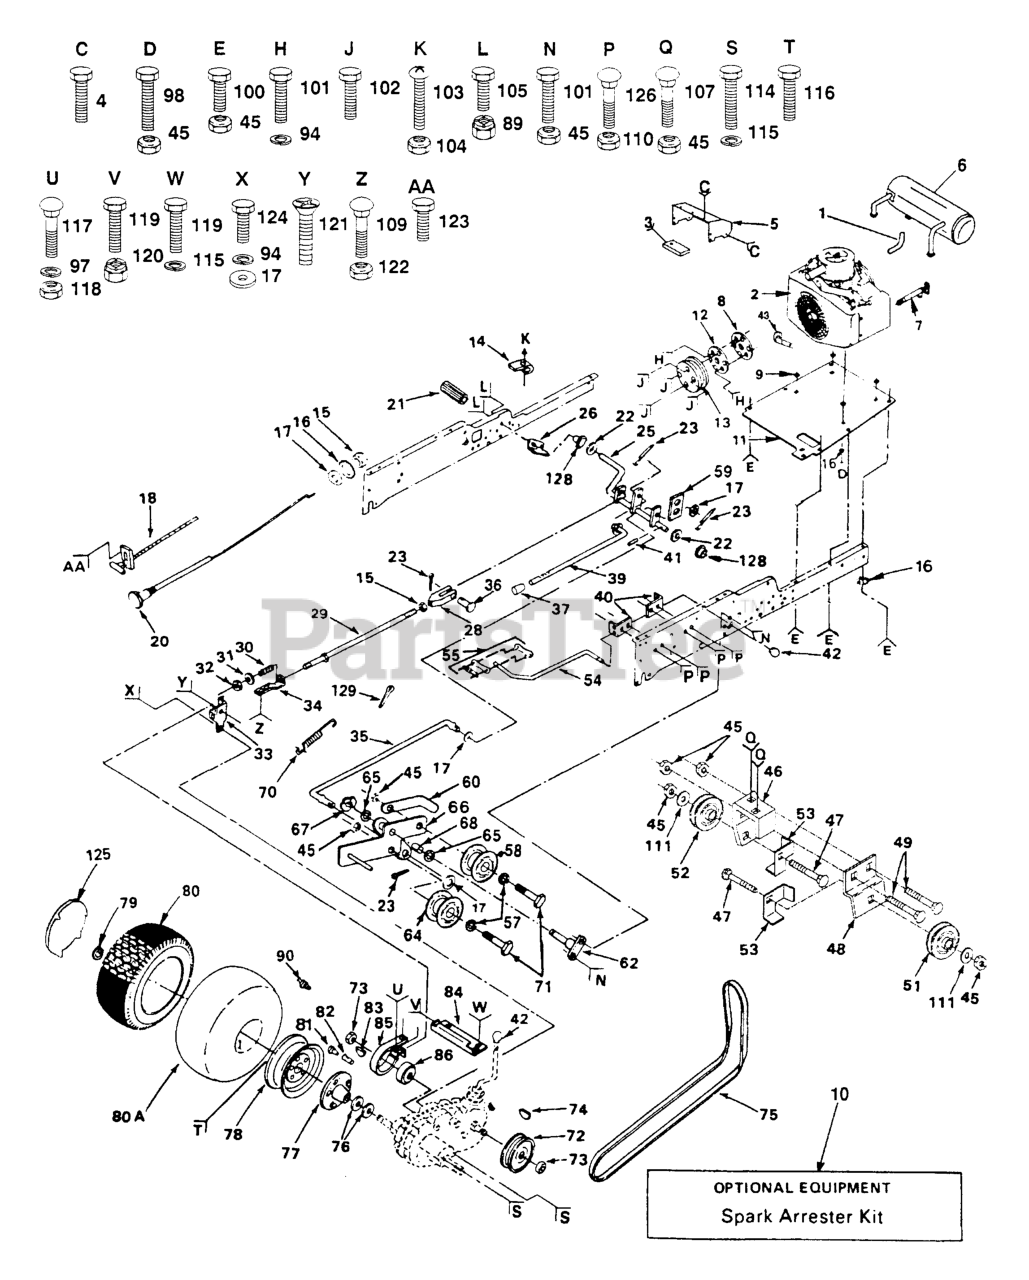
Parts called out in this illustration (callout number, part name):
1	EXHAUST OUTLET
2	Engine-18HP Kohler M18QS Type 24644
3	DUCT, LOWER ASS'Y
4	SCREW
5	DUCT,EXHAUST UPPE
6	MUFFLER EXHAUST
7	DRAIN VALVE
8	CHAFF GUARD T
10	SPARK ARREST KIT
11	BASE ENG. T
13	PULLEY GROUND DRI
14	ACT-SWITCH T
15	NUT
16	LOCKWASHER
17	WASHER
18	CONTROL THROTTLE
20	CHOKE CONTROL
21	PEDAL COVER T
23	COTTER PIN
25	SHAFT ASSY GT
26	BRKT SWITCH GT
29	BRAKE ROD T
31	WASHER
32	GRIPCO NUT
33	BRAKE BRKT ASSY T
34	GUIDE ROD T
35	ROD CLUTCH GTV
36	CLEVIS PIN T
37	PLUNGER CAP
39	BRAKE ROD T
40	ROD BRACKET GT
41	ROLL PIN STD
43	CLIP T
46	PIVOT BRKT GT
48	BRKT IDLER FLAT
49	Bolt, Carriage 3/8-16 x 3/4
51	IDLER-FLAT T
52	PULLEY V IDLR GTV
53	GUARD BELT
54	ROD SHIFT HI LO
55	CONNECTING LINK
57	Washer 13/32 x 7/8 x 13 Gauge
58	IDLER-FLAT GT
59	RETAINER SPRING
60	RETAINER BELT
62	BRACKET ASSY GTV
64	RP.IDLER GROOVED
66	BRACKET CLUTCH
68	BEARING LT (2 2)
70	SPRING EXT CLUTCH
71	BOLT
74	KEY
77	HUB T
79	Klip, Ring
80	TIRE HEAVY DUTY
80A	TUBE.23X9.5-12
82	VALVE STEM LT
83	KEY STD (1373) DANA
84	BRKT SUPPORT GT
85	BRAKE BAND ASM
86	BRAKE DRUM T
89	NUT.CROWNLOCK.1/4
90	ZERK FITTING M
94	WASHER, LOCK 3/8
97	LOCKWASHER
98	BOLT
101	BOLT
102	Screw, Hex 5/16-18 x 1
103	Screw, Fin #10-24 x 1
104	LOCKNUT
105	BOLT.HEX.1/4.X.3/4.DICHROMATE
107	BOLT
109	BOLT.CARR.SQNK.5/16-18UNC.X3/4
110	LOCKNUT
111	WASHER GT
114	BOLT
115	LOCKWASHER
116	BOLT M
118	NUT
119	BOLT
120	Nut, Crownlock 7/16-14
123	SCREW LT
124	BOLT
125	COVER,WHEEL
126	RP BOLT 5/16-18 X3/4 ZN/YEL GR
129	Pin, Cotter 1/4 x 1
